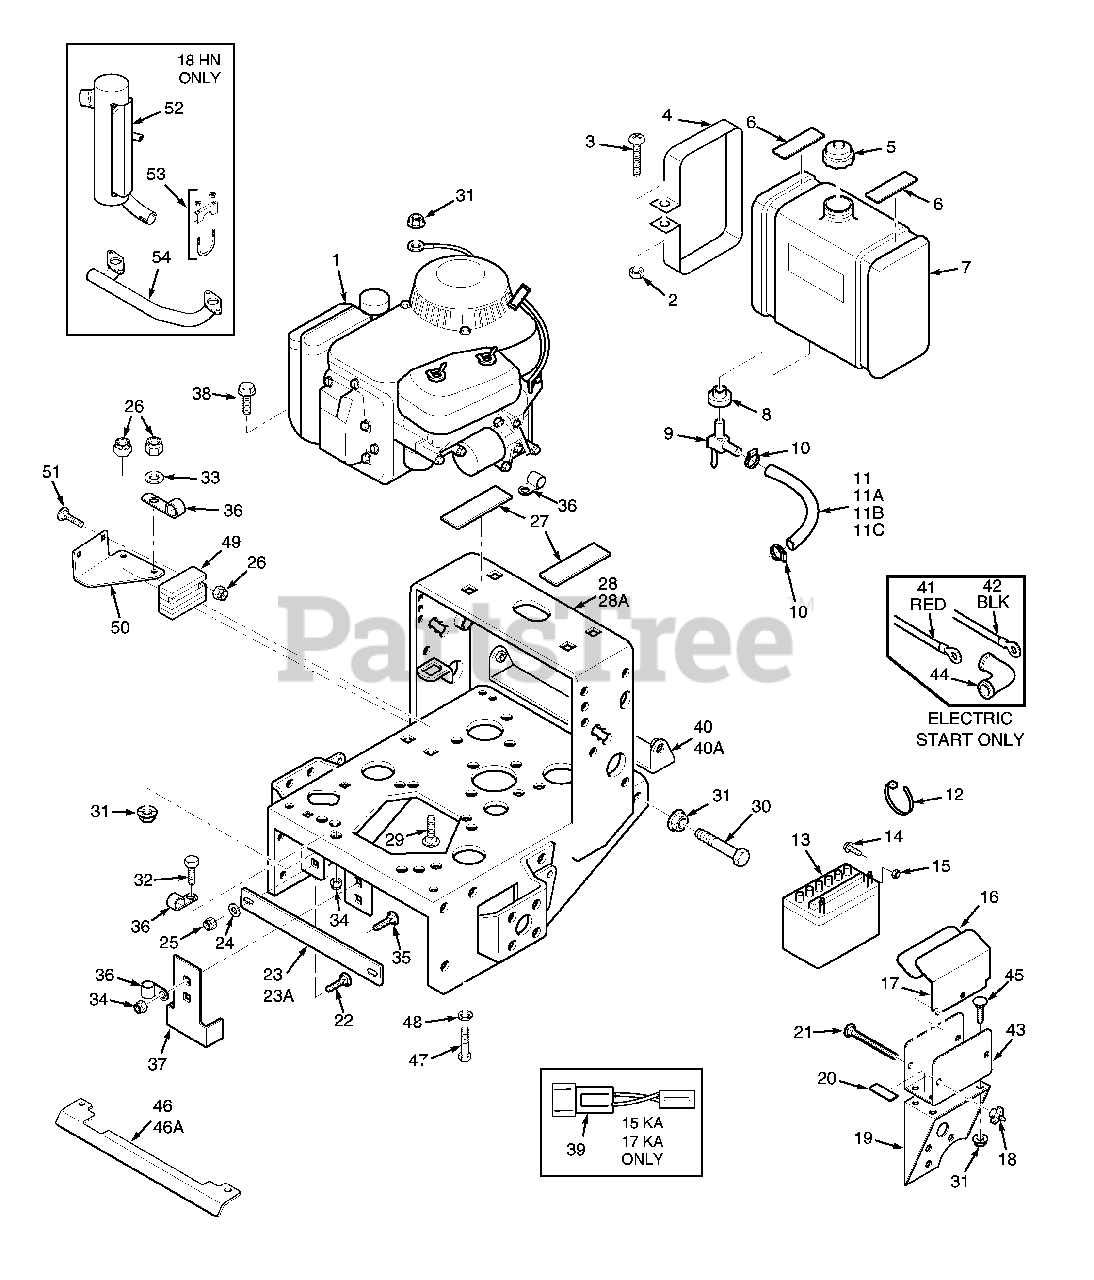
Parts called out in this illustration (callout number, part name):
1	Engine, 17KA Kawasaki
2	Hex Nut, 1/4-20
3	Screw, 1/4-20 x 2" Rnd. Hd. Phil.
4	Strap, Fuel Tank
5	Cap, Fuel Tank
6	Pad, Rubber-Fuel Tank - Upper
7	Fuel Tank Assy.
8	Bushing
9	Valve, Fuel Shut-off
10	Clamp, Fuel Hose
11	Fuel Hose, 1/4 ID x 23"
12	Cable Tie
13	Battery
16	Pad
17	Battery Cover
19	Battery Support
20	Pad, Rubber
21	Bolt, 1/4-20 x 6" Carriage
22	Carriage Bolt, 3/8-16 X 1-1/4"
23	Brace, (16" Small Frame)
23A	Brace, (20" Large Frame)
24	Flat Washer .391 x .938 x .105
25	Nut, 3/8-16 Elastic Stop
26	Nut, 1/4-20 Elastic Stop
27	Pad, Rubber-Fuel Tank Lower
28	Engine Deck, 16" Wide, w/decals
28A	Engine Deck, 20" Wide, w/decals
29	Bolt, 1/4-20 x 1-1/4" Carriage
30	Bolt, 5/16-18 x 2" Hex Head
31	Nut, 5/16-18 Serr. Flange
32	Hex Head Bolt, 5/16-18 x .75"
33	Flat Washer 1/4"
34	Nut, 5/16-18 Elastic Stop
35	Carriage Bolt, 5/16-18 x 1"
37	Clutch Bracket
38	Cap Scrw, 5/16-18 x 1.50" Sr. Flg
39	Wire Hrns. Adapter, 15 & 17KA
40	Pulley Guard, 16" Frame
40A	Pulley Guard, 20" Frame
41	Battery Cable, 31.5" Red
42	Battery Cable, 31.5" Black
43	Battery Box
44	Rubber Boot
46	Heatshield (16" Small Frame)
46A	Heatshield (20" Large Frame)
47	Bolt, 5/16-18 x 1" Serrated Flange Hex Head
49	Rectifier
50	Mounting Bracket, Rectifier
51	Bolt, 1/4-20 x 1" Carriage
52	Muffler
53	Clamp, Muffler
54	Manifold, Exhaust
